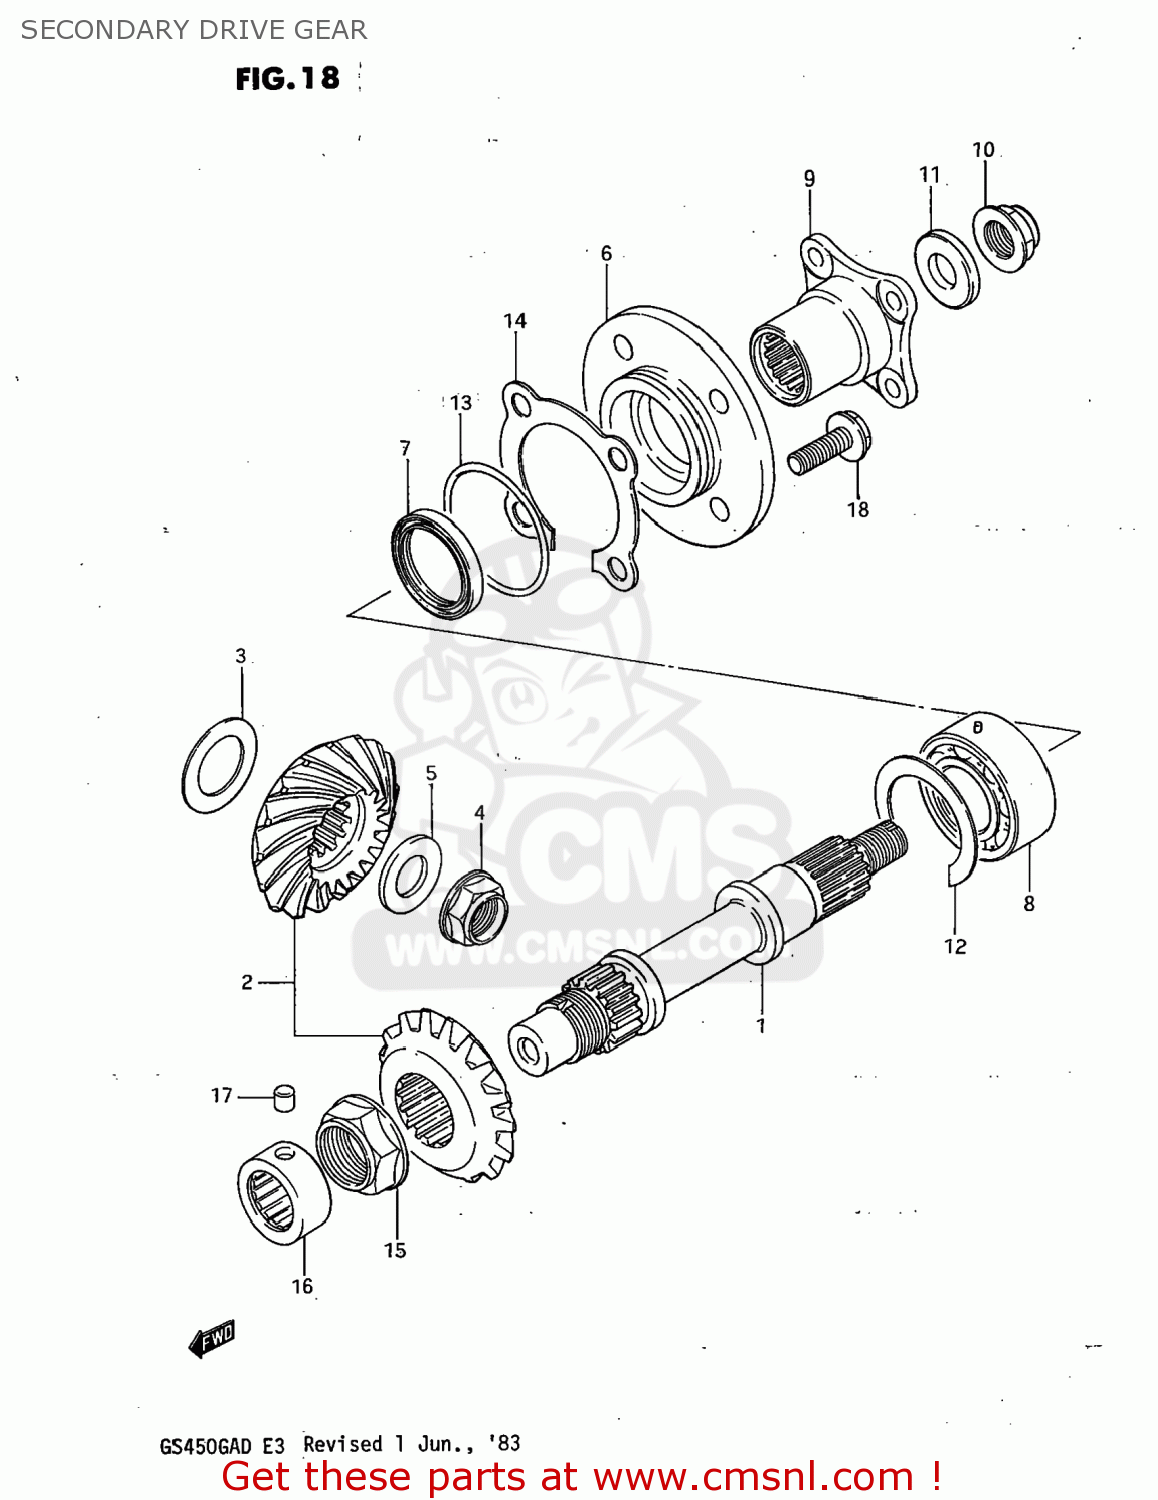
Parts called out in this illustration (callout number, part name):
1	SHAFT,SECONDARY DRIVEN
3	SHIM,SECONDARY DRIVE BEVEL
4	NUT
5	WASHER(16X30X3)
6	HOUSING,SECONDARY DRIVE
7	SEAL,OIL(32X42X7)
8	BEARING(25X52X21)
9	FLANGE,UNIVERSAL JOINT
10	NUT
11	WASHER(14X29X4)
12	SHIM,DRIVEN GEAR HOUSING
13	O-RING
14	SHAFT,SECONDARY DRIVEN,FRONT
15	NUT
16	BEARING(20X34X16)
17	PIN
18	BOLT
